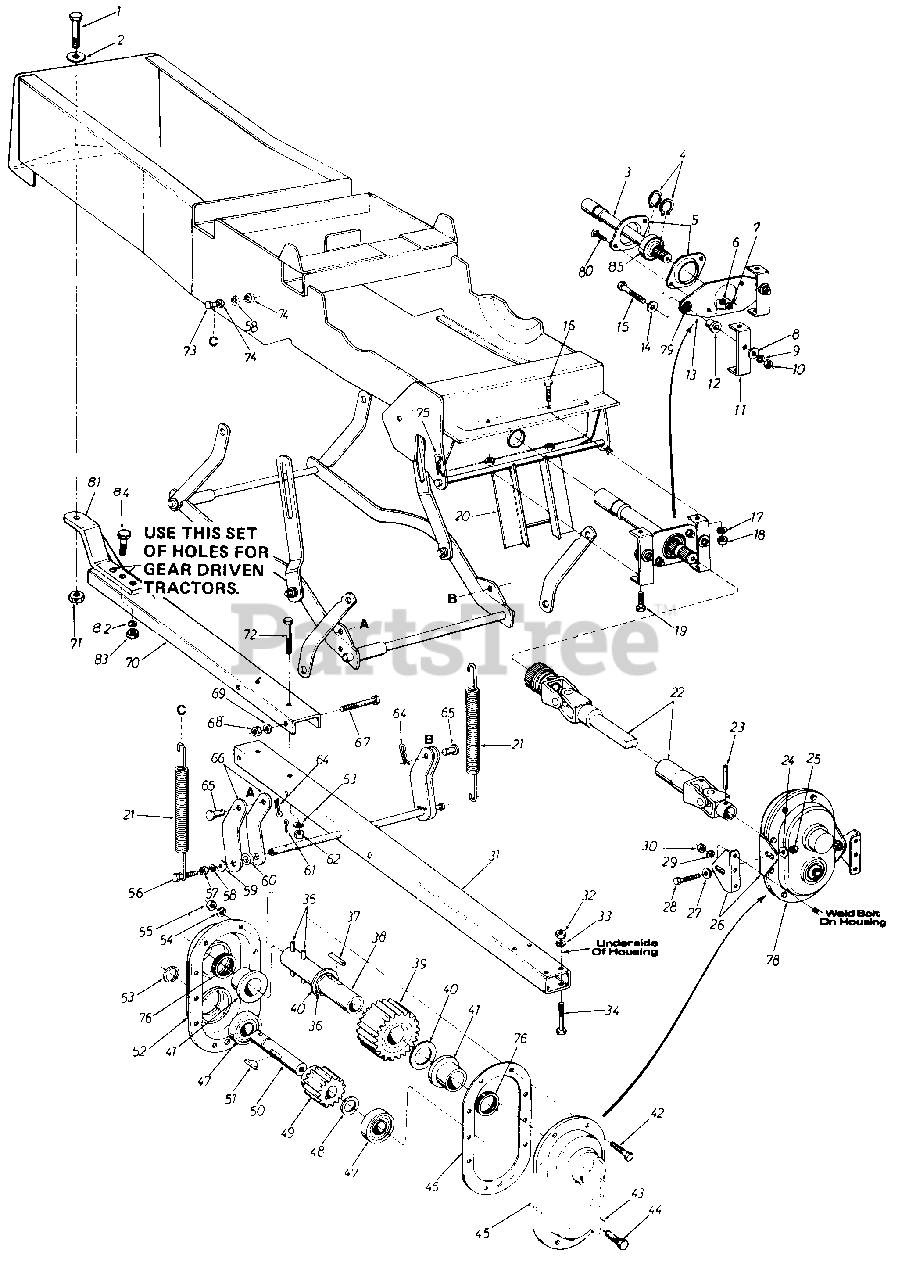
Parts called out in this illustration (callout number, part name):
1	Hex Scr. 5/8-18 x 1.31"Lg.
2	Fl.-Wash. .66" I.D. x 1.25" O.D. x .100
3	P.T.O. Shaft Extension Ass'y .
4	Retaining Ring 1.00" Dia. Shaft
5	Flangette Bearing
6	L.-Wash. 5/16" Scr.*
7	Hex Nut 5/16-18 Thd.*
8	Fl.-Wash. 3/8" I.D. x 1.00" 0. D
9	L Wash. 3/8" Scr.*
10	Hex Nut 3/8-24 Thd.*
11	P.T.O. Bearing Retainer Brkt.
12	Shoulder Spacer
13	P.T.O. Bearing Retainer Plate
14	Fl.-Wash. 3/8" I.D. x 1.00 O.D.
15	Hex Scr. 3/8-24 x 1.50" Lg.*
16	Hex Scr. 3/8-16 x .75" Lg.*
17	L.-Wash. 3/8" Scr.*
18	Hex Nut 3/8-16 Thd.*
19	Hex Scr. 3/8-16 x .75" Lg.*
20	Guide Bracket Ass'y.
21	Helper Spring .94 O.D. x 7.38" Lg.
22	Universal Drive Shaft Ass'y.
23	Spring Pin Spirol 5/16" x 2.50" Lg.
24	Belleville Wash. .341 I.D. x .88 O.D.
25	Hex Nut 5/16-18 Thd.*
26	Gear Box Support Bracket
27	Belleville Wash. .34 I.D. x .88 O.D.
28	Hex Scr. 5/16-18 x .75" L.g*
29	L.-Wash. 5/16" Scr.*
30	Hex Nut 5/16-18 Thd.*
31	Lift Shaft Ass'y.
32	Hex Ins. Jam L.-Nut 3/8-24 Thd.
33	L.-Wash. 3/8" Scr.*
34	Hex Scr. 3/8-24 x 2.75"Lg.*
35	Spring Pin Spirol 5/16" Dia. 1.75" Lg.
36	Snap Ring for 1.25" Dia. Shaft
37	Sq. Key 1/4" x 1.00" Lg.
38	Gear Shaft
39	28 Teeth Spur Gear
40	Fl.-Wash. 1.31" I.D. x 2.00" O.D. x .060
41	Flange Bearing 1.25" I.D. 1.75" O.D.
42	Hex Screw 1/4-28 x .88 "Lg.
43	Fl-Wash. .40" I.D. x 1.25" O.D. x .160
44	Hex L.-Scr. 3/8-24 x 1.00"Lg.
45	Complete Gear Housing Half-L. H.
46	Gasket
47	Ball Bearing 1.00" I.D. x 2.00" O.D.
48	Fl.-Wash. 1.03" I.D. x 1.63" O.D. x .090
49	15 Teeth Spur Gear
50	Input Shaft
51	Woodruff Key 1/4 x 3/4" Dia.
52	Compiete Gear Housing Half-R. H.
53	Snap Ring for 1.00" Dia. Shaft
54	L.-Wash. 1/4" Scr.*
55	Hex Nut 1/4-28 Thd.
56	Hex Scr, 5/16-18 x 1.75" Lg.
57	Hex Nut 5/16-18 Thd.*
58	L.-Wash. 5/16" Scr.*
59	Fl.-Wash. .344 I.D. x 1.12 O.D. x .125
60	Spacer .81" I.D. x 1.00" O.D. x .31
61	Cotter Pin 5/32" Dia. x 1.00" Lg.*
62	Hex Ins. Jam L.-Nut 3/8-24 Thd.
63	L.-Wash. 3/8" Scr.*
64	Intern. Cotter Pin 1/2"Dia.
65	Clevis P.in .500" Dia.
66	Lift Bracket
67	Hex Scr. 3/8-24 x 4.50"Lg.*
68	Hex Ins. Jam L.-Nut 3/8-24 Thd.
69	L.-Wash. 3/8" Scr.
70	Lift Bracket
71	Hex Ins. Jam L.-Nut 5/8-18 Thd.
72	Hex Scr. 3/8-24 x 2.75"Lg.*
73	Hex Scr. 5/16-18 x 1.75" Lg.*
74	Hex Nut 5/16-18 Thd.*
75	Intern. Cotter Pin 3/4"Dia.
76	Oil Seal 1.25" I.D. x 1.75" O.D. x .26
78	Gear Box Ass'y. Comp.
79	Rubber Grommet .50" I.D.
80	Carriage Bolt 5/16-18 x .75" Lg.*
83	Hex Nut 1/2-13 Thd.
84	Hex Scr. 1/2-13 1-1/4 Lg.
85	Ball Bearing
